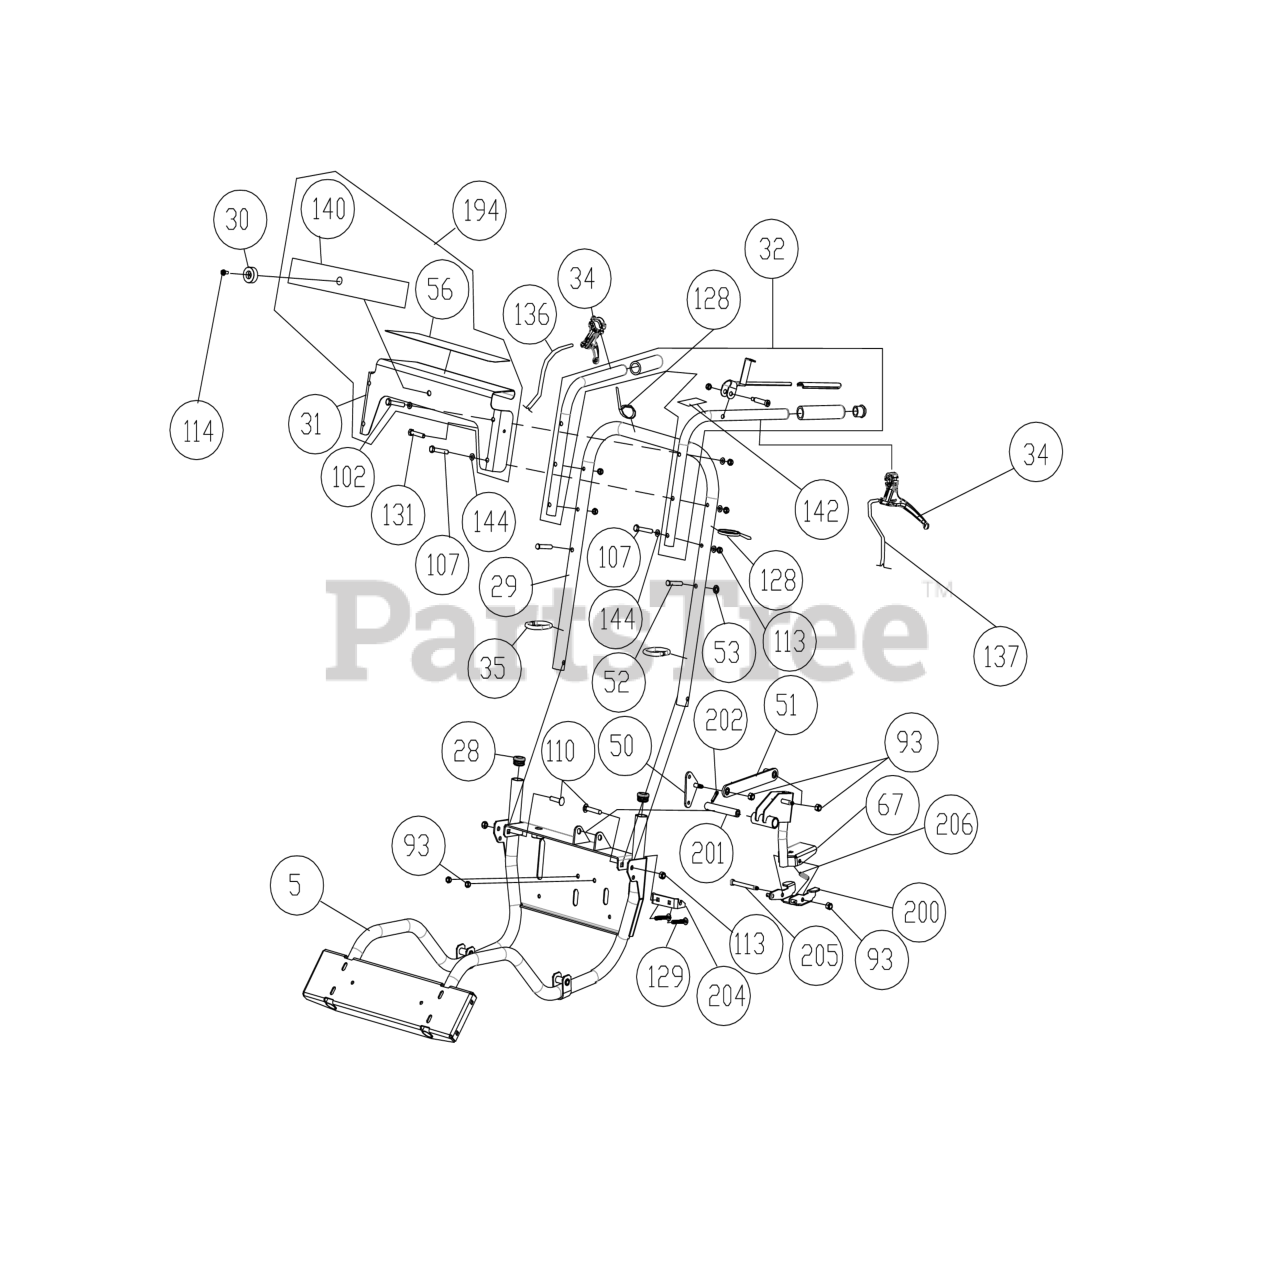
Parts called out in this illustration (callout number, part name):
5	FRAME SUPPORT OS900SP WA
28	PLUG TUBE INSERT 1.25" O.D.
29	HANDLE FOLDING
30	BUMPER RECESS
31	BRACKET CONSOLE
32	HANDLE FOLDING
34	CONTROL MAGURA
35	LOOP FOLDING HANDLE
50	ENGINE BRACKET WA OS901SP
51	LINKAGE, FOOT CONTROL WA OS901SP
52	PIN CLEVIS 3/8 X 2.125
53	RETAINER 3/8" BOLT PUSH NUT
56	LABEL INSTRUCTION
67	PEDAL ASSY (PLUG/TREAD/BUSHINGS) OS901SP
93	NUT LOCK 5/16"-18 HEX Z/P
102	SCREWCAP 3/8"-16 X 1 3/4" HCS ZP
107	SCREWCAP 3/8"-16X3" HCS ZP
110	BOLT CARRIAGE 3/8"-16 X 2" ZP
113	NUT LOCK 3/8"-16 HEX
114	SCREW SELF TAP 1/4"-20 X 5/8" HWH TYPE F
115	WASHER 1/4"SAE9/32"X5/8"X1/16"
117	NUT LOCK 1/4"-20 HEX Z/P
129	BOLT CARRIAGE 5/16"-18 X 3/4" ZP
131	SCREWCAP 1/4"-20 X 1" HCS ZP
136	SEE: 351219-S
137	SEE: 351271-S
142	LABEL CLUTCH BLADE
144	WASHER 3/8"FC7/16"X1"X5/64"
200	RELEASE PEDAL WA OS901SP
201	SHAFT, INNER PIVOT
202	PIN COTTER 1/8" X 1" Z/P
204	BRACKET, PIN CATCH
205	BOLT SHOULDER, 3/8" DIA. X 3.25" LONG
206	SPRING, RELEASE PEDAL
